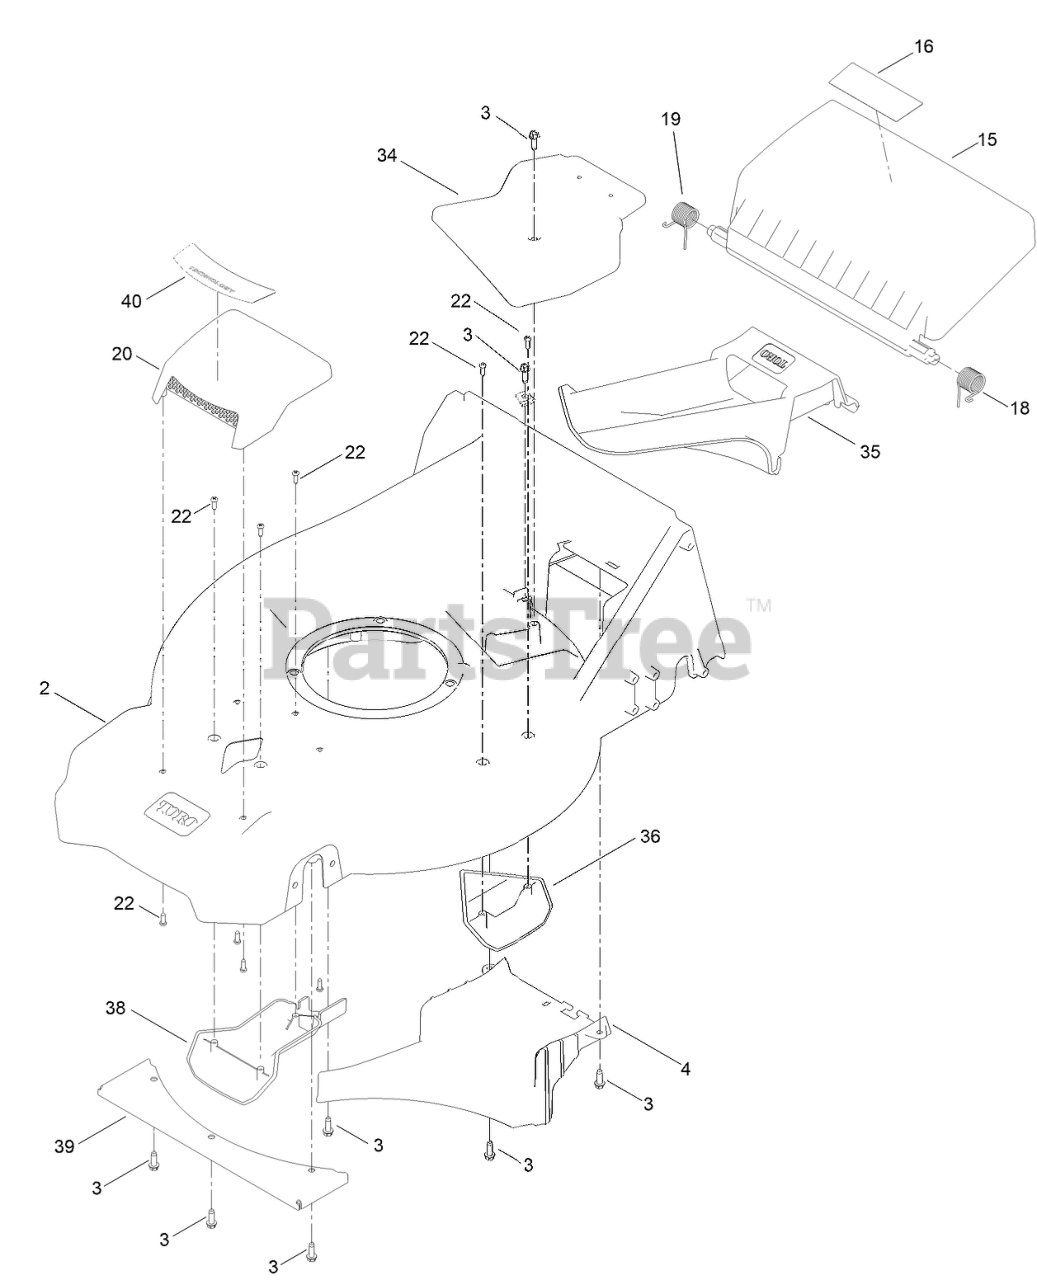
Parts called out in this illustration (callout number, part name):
2	HOUSING ASM
3	SCREW-HWHTF
4	RAMP-DISCHARGE
15	DOOR-REAR
16	DECAL-WARNING
18	SPRING-TORSION, LH
19	SPRING-TORSION, RH
20	ASM-COVER, TOP INTAKE
22	SCREW-PLASTIC, PPH
34	COVER-BELT, TOP
35	PLUG-MULCH
36	KICKER-HOUSING
38	COVER-INTAKE, BOTTOM
39	PLATE-COVER, CE
